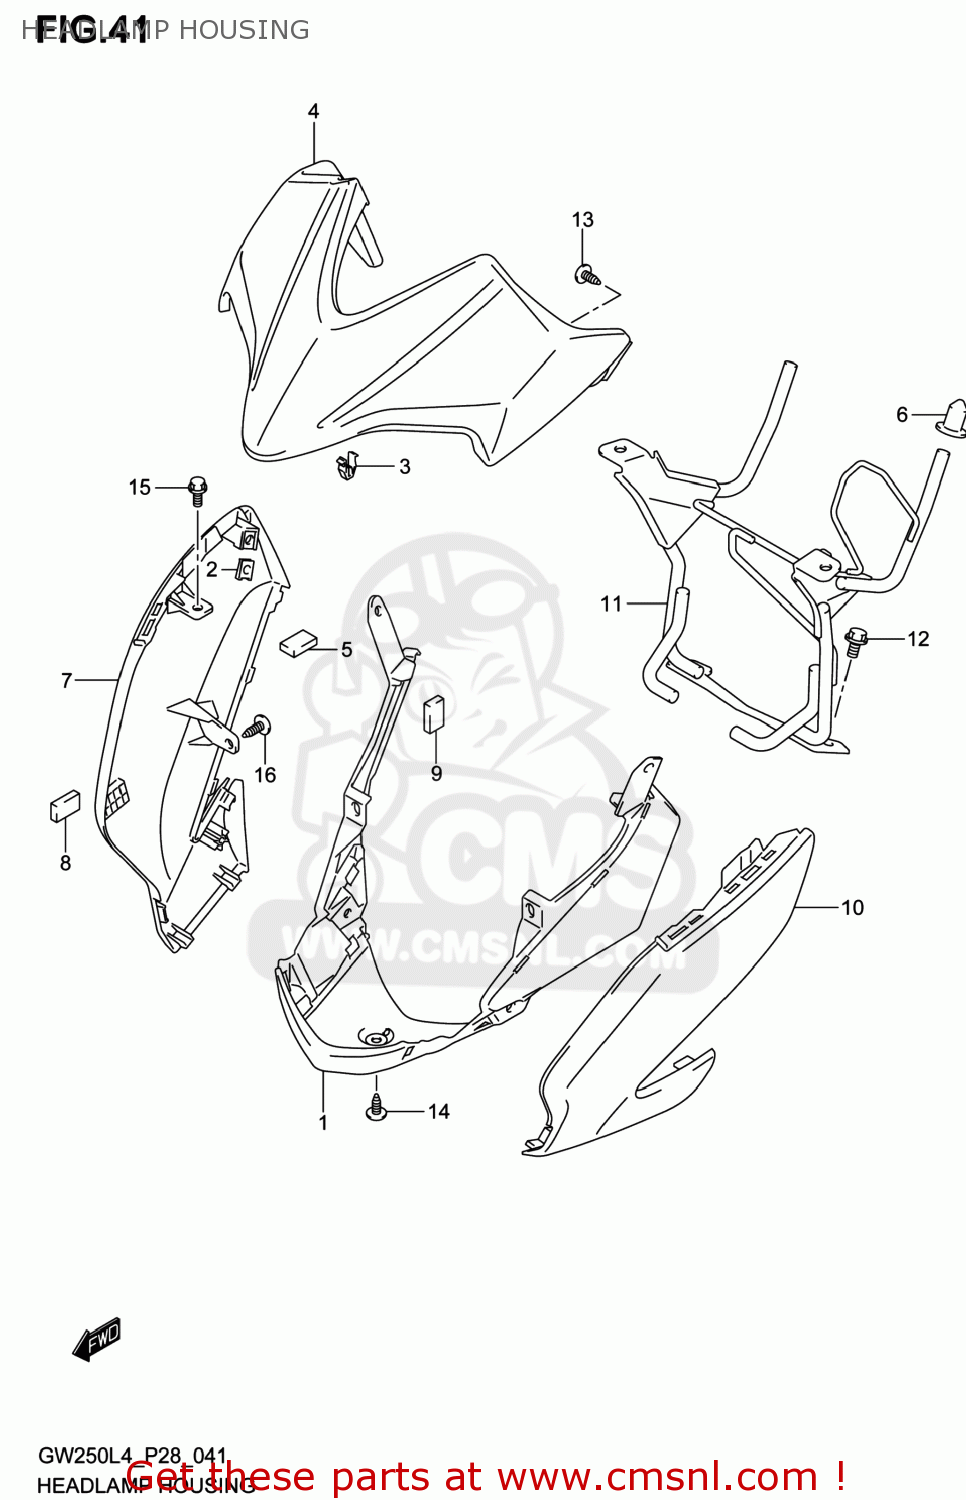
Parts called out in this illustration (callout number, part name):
1	COVER,HEADLAMP LWR
2	NUT,HEADLAMP
3	CLIP,COVER & LEG FR
4	COVER,HEADLAMP UPPER
5	CUSHION,HEADLAMP UPR
6	CUSHION,HOUSING BRACE
7	COVER,HEADLAMP SIDE,R
8	CUSHION,HEADLAMP SIDE
9	CUSHION,HEADLAMP SIDE
10	COVER,HEADLAMP SIDE,L
11	BRACE,HEADLAMP HOUSING
12	BOLT
13	SCREW
14	SCREW
15	SCREW
16	SCREW
